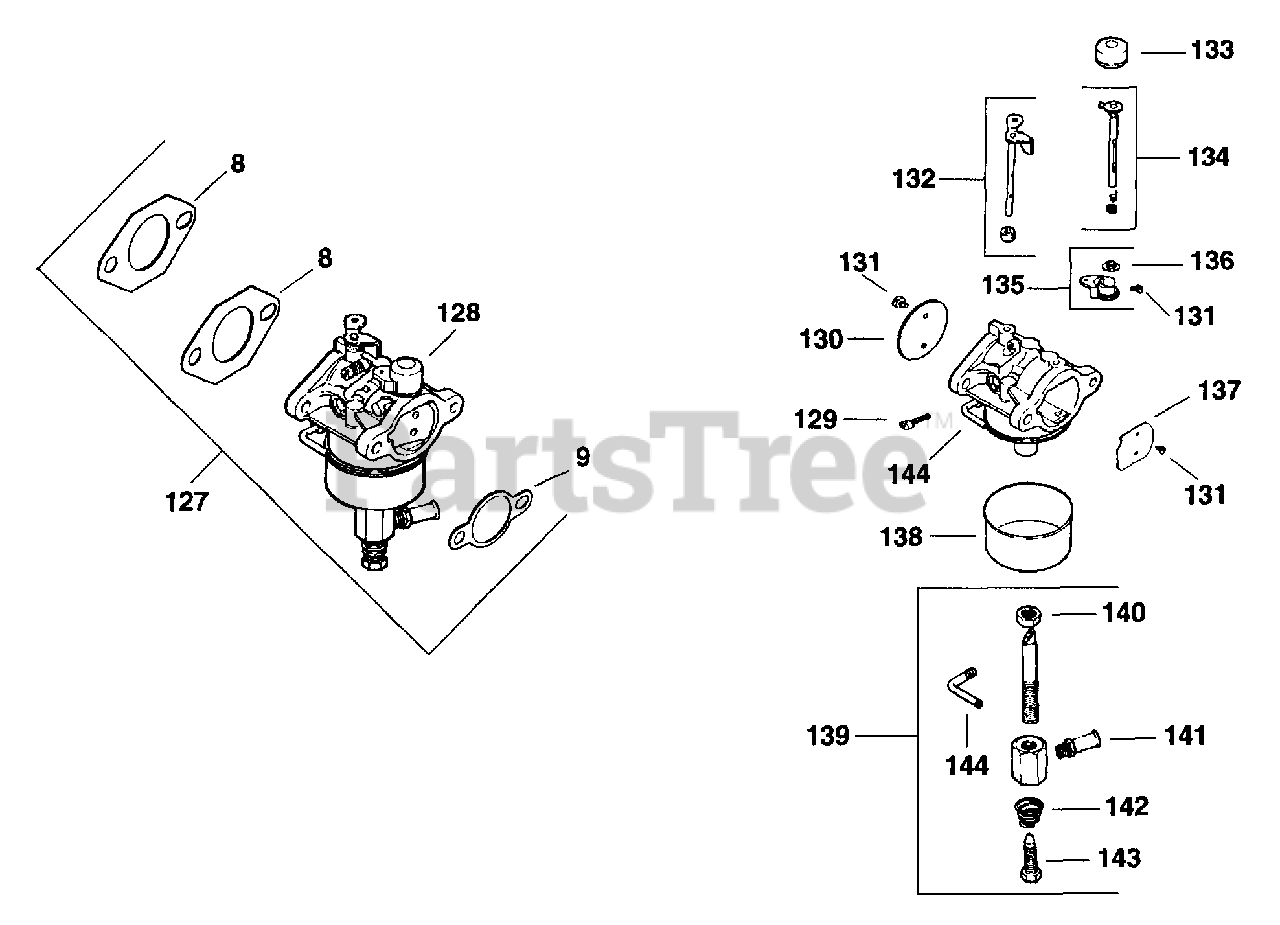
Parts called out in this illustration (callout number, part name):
8	GASKET, CARBURETOR
9	GASKET, AIR CLEANER BASE
127	KIT, CARBURETOR W/GASKET LPG
131	SCREW, VALVE
132	SHAFT, THROTTLE
133	CAP, CHOKE LEVER
134	SHAFT, CHOKE
135	KIT, CHOKE LEVER REPAIR - USE 12 757 32-S
136	BUSHING, CHOKE
137	PLATE, CHOKE
139	KIT, CARBURETOR REPAIR
140	NUT, 3/8-24 JAM, GRADE 2 - DISC.
141	FITTING, HOSE TO PIPE
142	SPRING, IDLE ADJUSTMENT
143	SCREW, POWER ADJUSTMENT
144	TUBE, VACUUM
